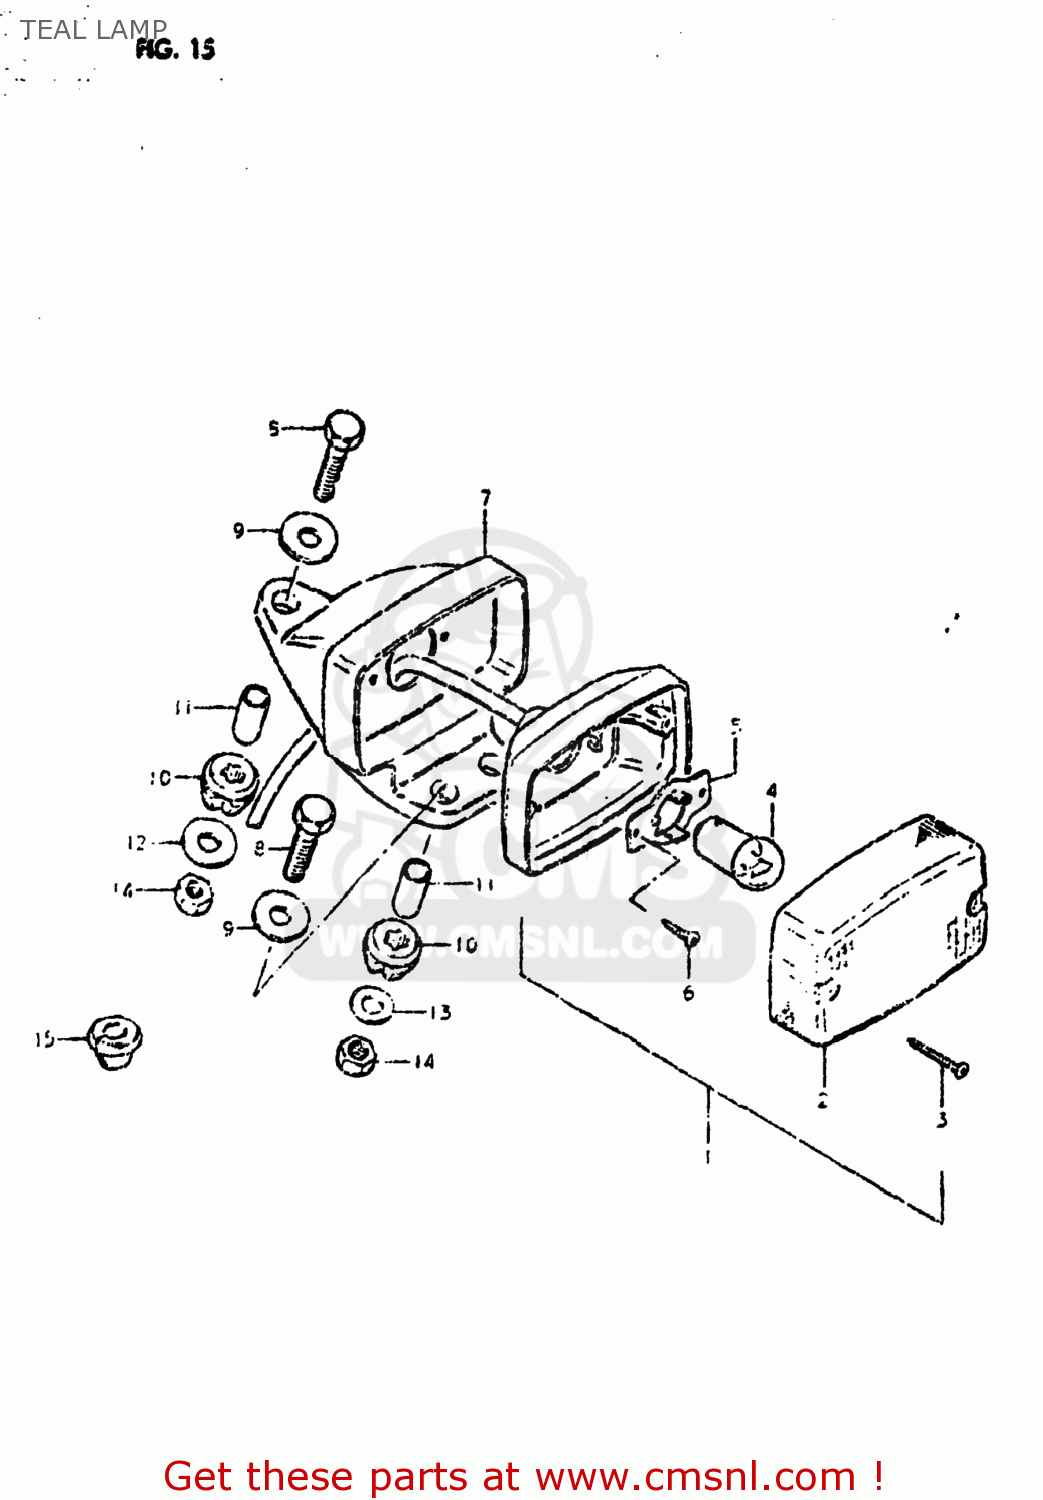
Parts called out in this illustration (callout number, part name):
1	LAMP UNIT,TAIL
2	LENS
3	SCREW
4	BULB(6V5W,TOKAI DENSO)
5	PLATE,TURN SIGNAL
6	SCREW,REAR COMBINATION LAMP LENS
7	BRACKET,REAR COMBINATION LAMP
8	BOLT
9	WASHER (6.5X20X1.2)
10	CUSHION
11	SPACER
12	WASHER (6.5X20X1.2)
13	WASHER
14	NUT
15	GROMMET
